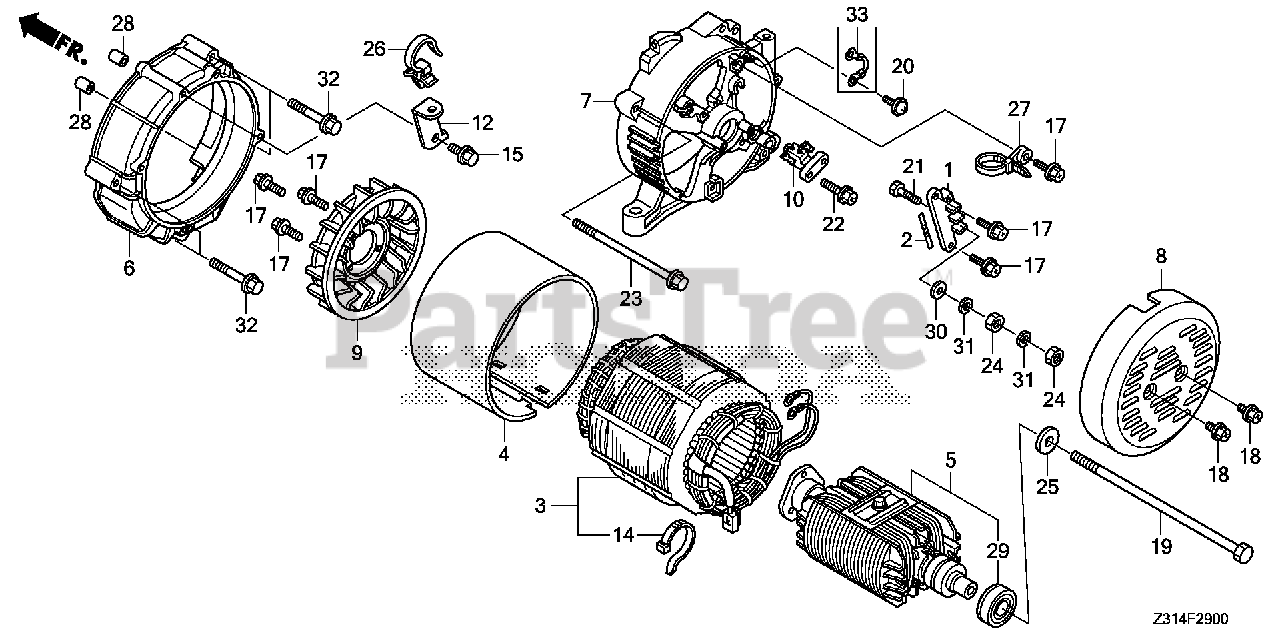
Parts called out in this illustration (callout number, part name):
1	TERMINAL, VOLT CHANGE
2	MARK, VOLT
3	STATOR ASSY.
4	COVER, STATOR *NH105* (MAT BLACK)
6	HOUSING, FR.
7	HOUSING, RR.
8	COVER, GENERATOR END *NH105* (MAT BLACK)
9	FAN, GENERATOR COOLING
10	BRUSH ASSY.
12	BRACKET, WIRE HARNESS CLIP
14	TIE, CABLE (C)
15	BOLT, FLANGE (6X12) (CT200)
17	SCREW, TAPPING (5X14)
18	SCREW, TAPPING (5X12)
19	BOLT, HEX. (10X237)
20	SCREW, PAN (5X12)
21	BOLT, HEX. (5X20)
22	SCREW, TAPPING (5X18)
23	BOLT, FLANGE (6X147)
24	NUT, HEX. (5MM)
25	WASHER (10.5MM)
26	CABLE, STRAP
27	TIE, CABLE
28	PIN, DOWEL (8X12)
29	BEARING ASSY. (6204)
30	WASHER, PLAIN (5MM)
31	WASHER, SPRING (5MM)
32	BOLT, FLANGE (8X60)
